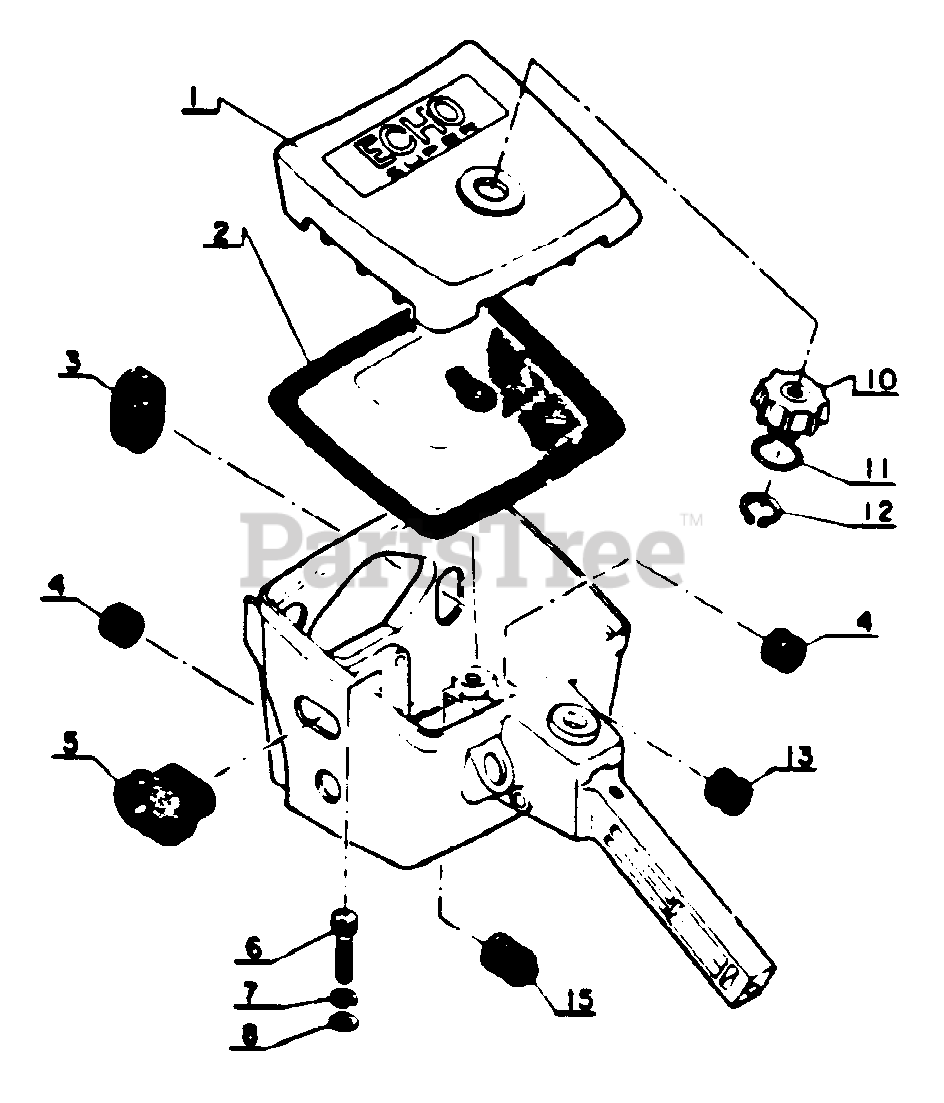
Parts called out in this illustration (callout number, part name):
1	COVER, AIR FILTER
2	FILTER, AIR
5	GROMMET
6	BOLT
6	BOLT - 5×20
7	WASHER, SPRING 5
8	WASHER, FLAT 5.5×10×0.8
9	PLATE, NAME
10	WINGNUT
11	O-RING
13	GROMMET, RUBBER
16	SEAL, DUST
